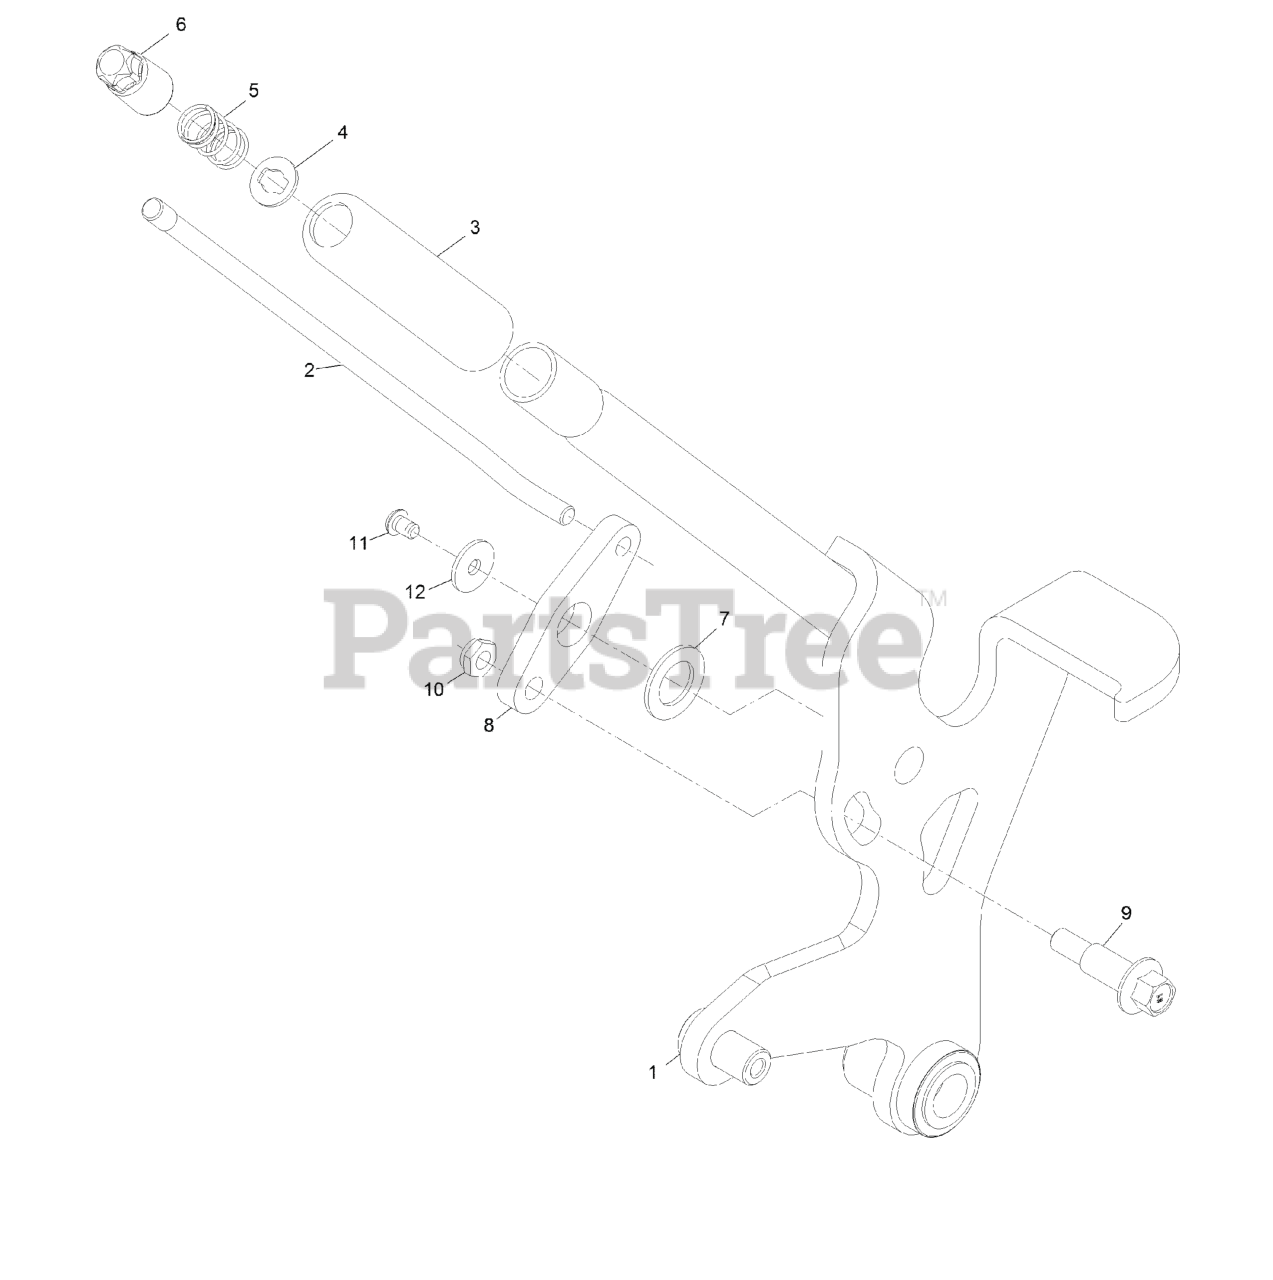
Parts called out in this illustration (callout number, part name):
1	ASM, Lever W/ Bushings
2	Linkage, HOC Lever
4	WASHER-SPECIAL
5	SPRING-COMPRESSION
6	BUTTON, PUSH
7	WASHER-NYLON
8	Arm, Transport
9	SCREW-BH
11	SCREW, 1/4-20 X 3/8 PH TORX
